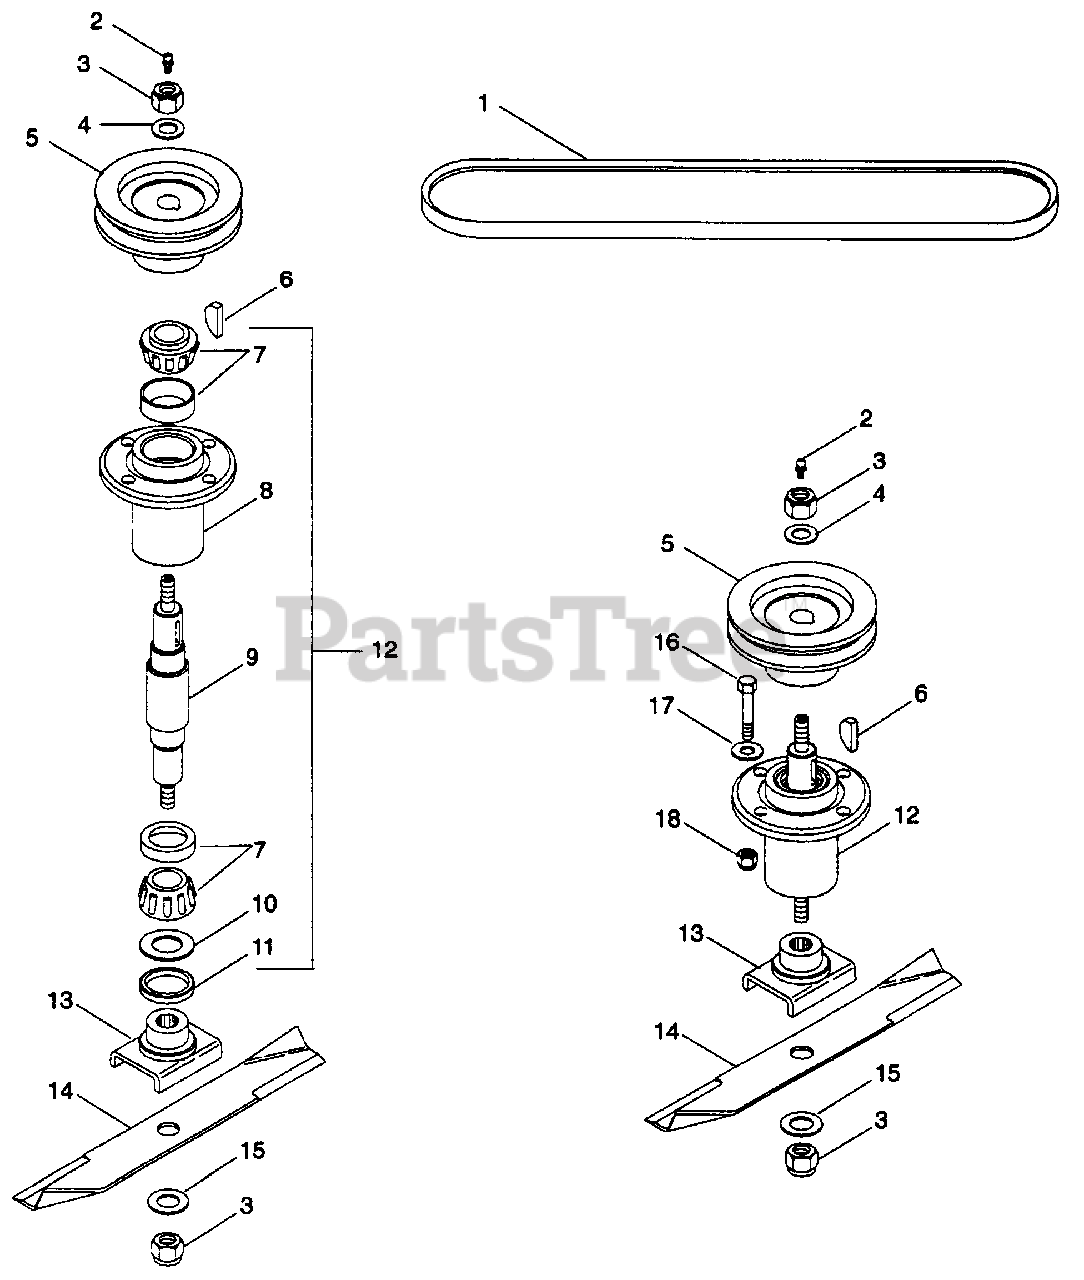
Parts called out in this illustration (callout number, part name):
1	V-BELT A-RMA 34.65 X 33/64
2	FTG, LUBE 1/8
3	NUT-LK-NYL .625-11 PL
4	WSHR-FL-STL .687 X 1.312 X .135
5	SPINDLE SHEAVE
6	KEY, WDRF .25 X 1 HRD # 15
7	ASM, BEARING CUP & CONE
8	HSG, BEARING
9	SHFT, SPINDLE
10	WSHR-FL-STL .97 X 1.865 X .03
11	SL, STEEL
12	ASM, SPINDLE
13	WLDMT, BLADE CRDL
14	BLD, 36 MOWER
15	WSHR-FL-STL .656 X 1.312 X .095 PL
16	BLT-HEX .38-16 X 1.25 PL GR 5
17	WSHR-FL-STL .438 X 1.000 X .083
18	NUT-LK-NYL .375-16 PL
NS	BELT FINGER, PRO 150 DECK
